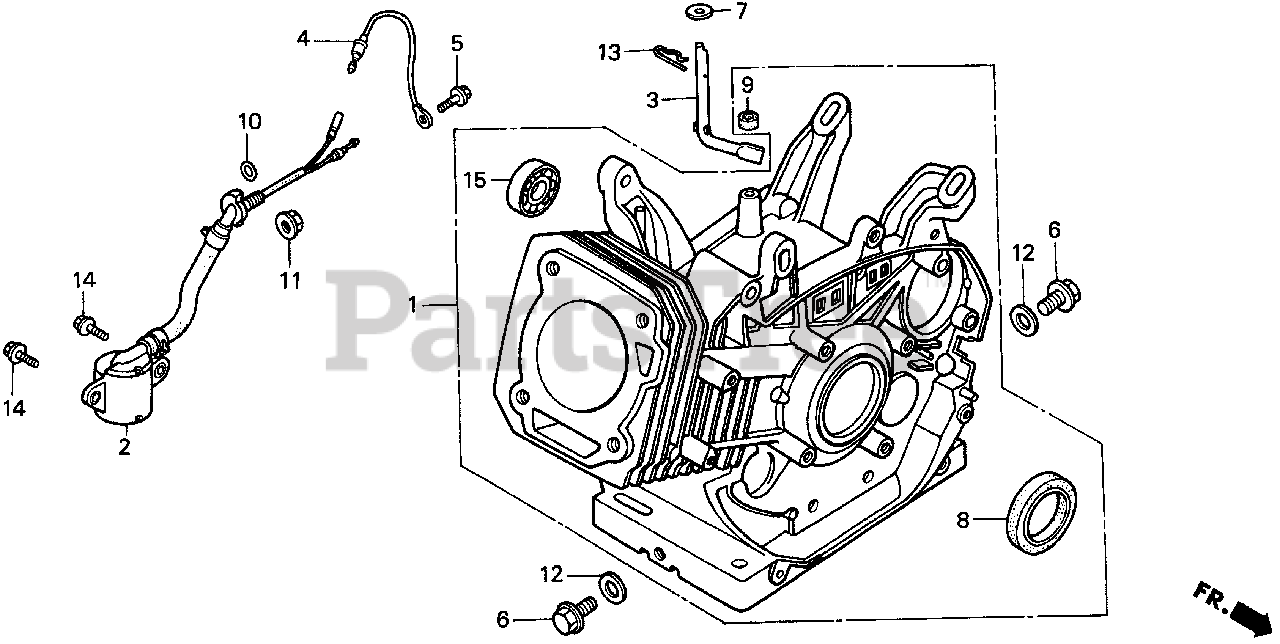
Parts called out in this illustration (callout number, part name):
1	CYLINDER ASSY.
1	CYLINDER ASSY. (L04)
2	SWITCH ASSY., OIL LEVEL
3	SHAFT, GOVERNOR ARM
4	SUB-HARNESS
5	BOLT, FLANGE (6X12) (CT200)
6	BOLT, DRAIN PLUG
7	WASHER (8.2X17X0.8)
8	OIL SEAL (35X52X8)
9	OIL SEAL (8X14X5)
10	O-RING (13.5X1.5) (ARAI)
11	NUT, FLANGE (10MM)
12	WASHER, DRAIN PLUG (12MM)
13	PIN, LOCK (8MM)
14	BOLT, FLANGE (6X12)
15	BEARING, RADIAL BALL (6202)
